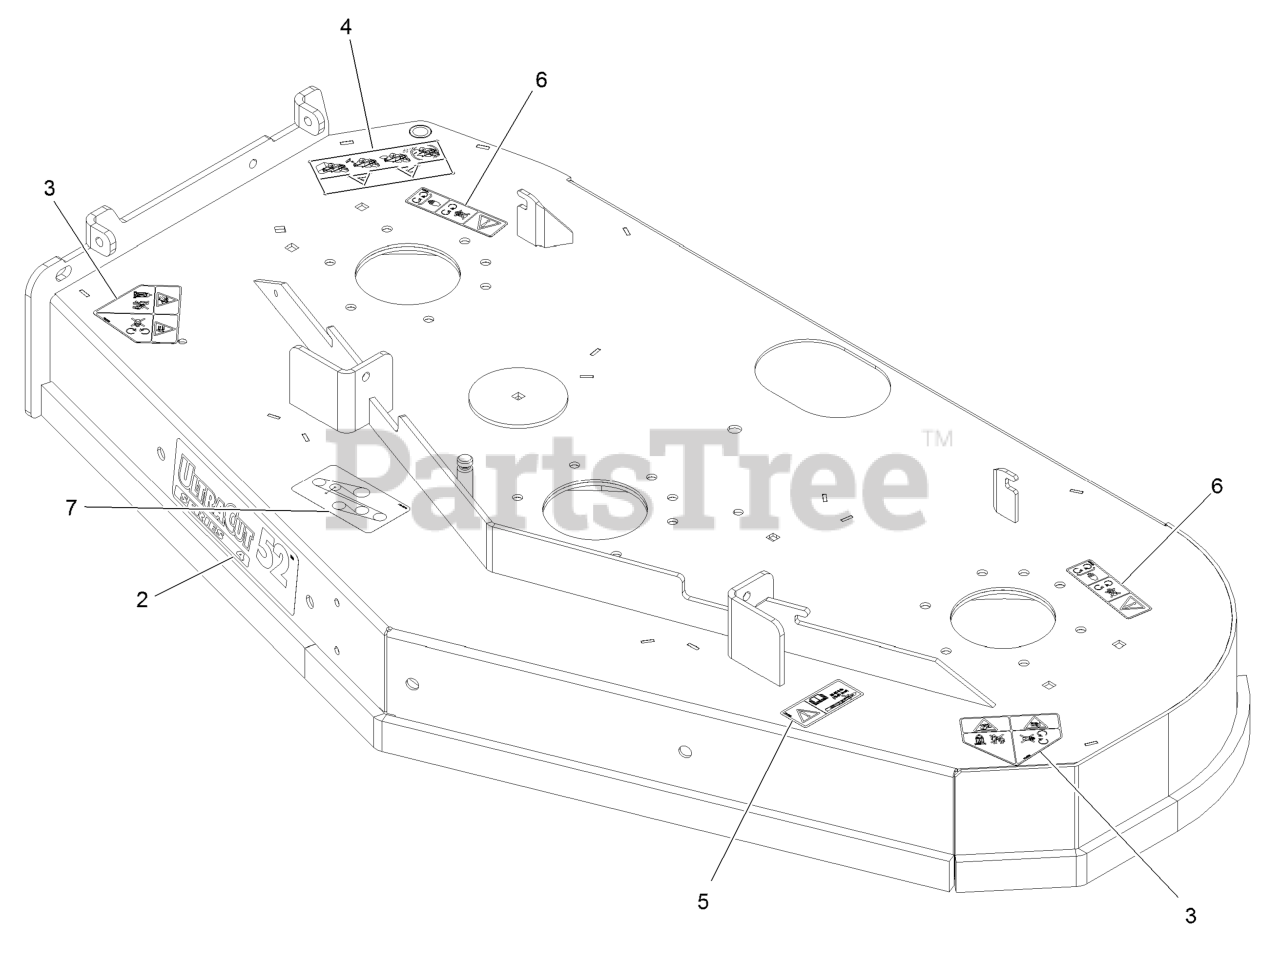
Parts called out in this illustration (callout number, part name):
2	DECAL,ULTRACUT 52 SERIES
3	DECAL-DANGER
4	DECAL-WARNING, BAGGER
5	DECAL-BOLT TORQUE
6	DECAL-COVER, MISSING
7	DECAL-BELT ROUTING
